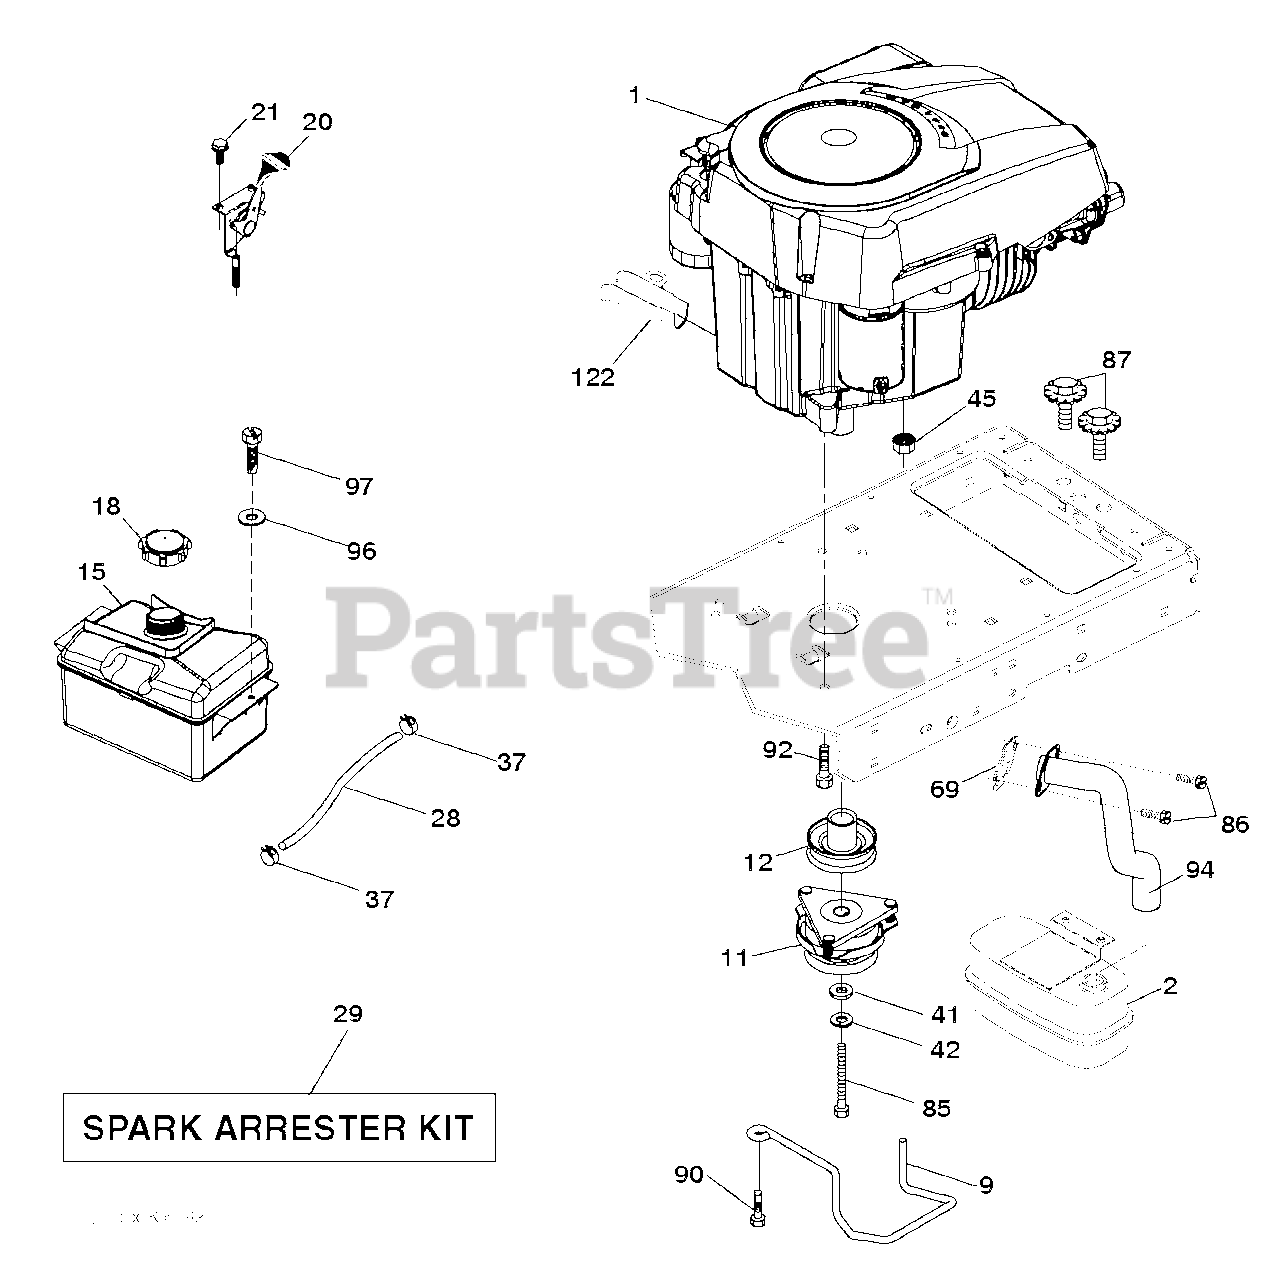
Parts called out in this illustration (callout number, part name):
2	MUFFLER.SINGLE.CYL.KOHL/B&S
9	KEEPER.BELT.ENGINE.4.2
11	RB.CLUTCH.OGURA.4.4.PD
12	PULLEY.ENGINE.TUFFTORQ
15	RP TANK FUEL FRT 1.5 GAL
18	CAP ASM.FUEL.2.25"FR.
20	CONTROL.TH/CK.C.
21	SCREW.#10 X 0.750.BOS
28	LINE.FUEL.20
29	KIT.SPARK ARRESTOR 794945 B&S
37	HOSE CLAMP
42	LOCKWASHER
45	NUT
69	GASKET.EXHAUST.KOHLER
85	BOLT HEX 7/16-20X4-1/4"
86	SCREW.SOCKET HD.5/16-1
87	BOLT, 5/16-18 X 1 3/4
90	SCREW 3/8-16X1
92	SCREW 3/8-16X1
94	RP.TUBE.EXHAUST.KOHL.COURAGE
97	SCREW HEXWSHR 1/4-20X3/4
122	EXTENSION DRAIN OIL
